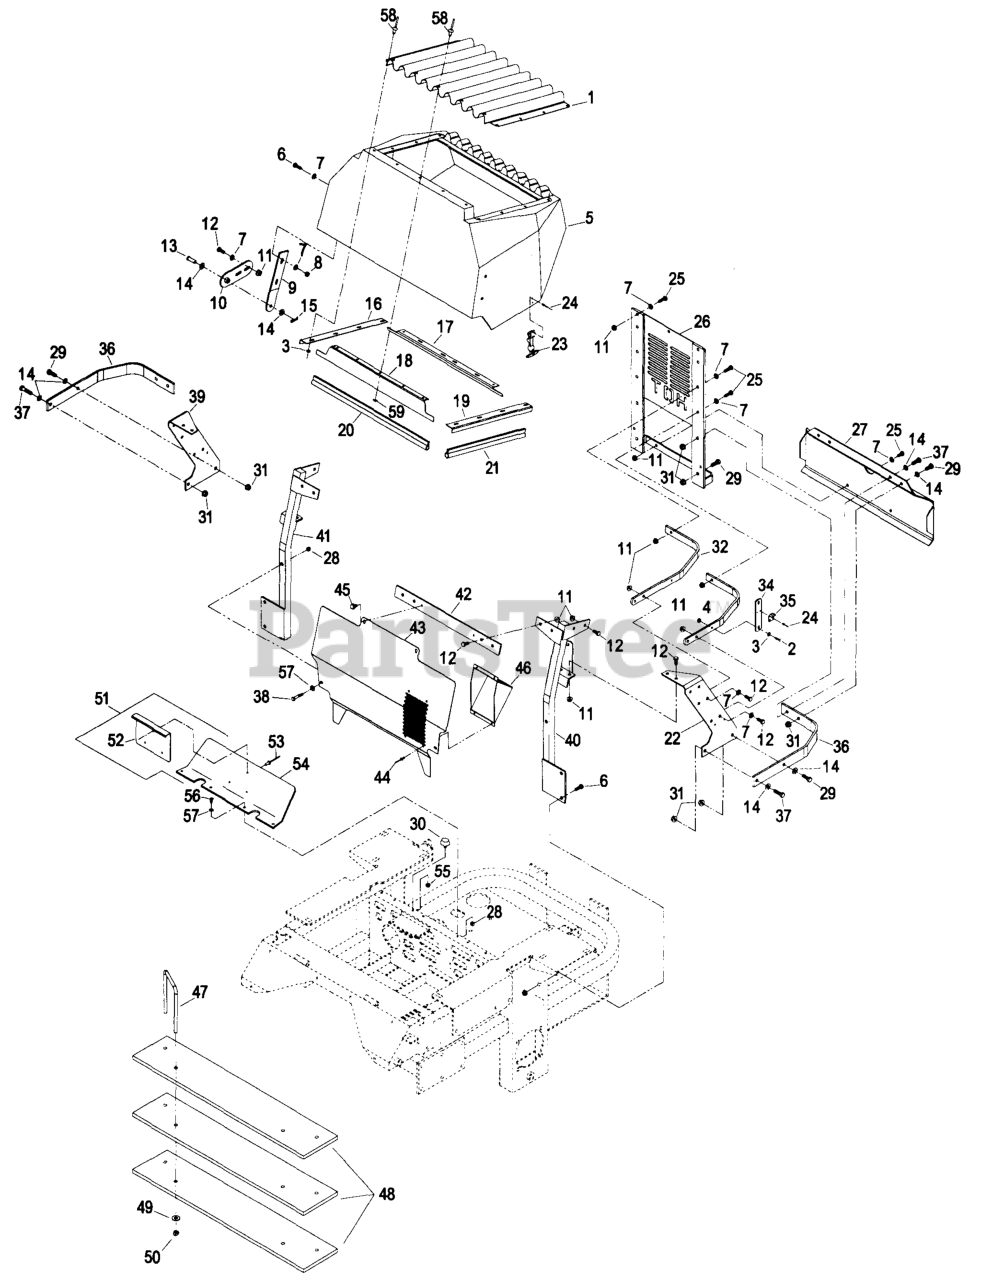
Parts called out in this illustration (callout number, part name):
1	SCREEN-RADIATOR
9	PLATE-HINGE, HOOD
10	SHACKLE-HINGE
13	PIN-CLEVIS
15	PIN-COTTER
16	ANGLE-RADIATOR, RH
17	ANGLE-RADIATOR, BOTTOM
18	ANGLE-RADIATOR, TOP
19	ANGLE-RADIATOR, LH
20	SEAL-TRIM
21	SEAL-TRIM
23	LATCH-RUBBER
34	Bar, Latch Hook
40	BRACE-RADIATOR, LH
43	Deflector, Air
44	Pop Rivet - Stl 3/16 X .250
46	PLENUM-INTAKE, AIR
52	Shield, Lift
53	RIVET-POP
59	WASHER-SPRING
